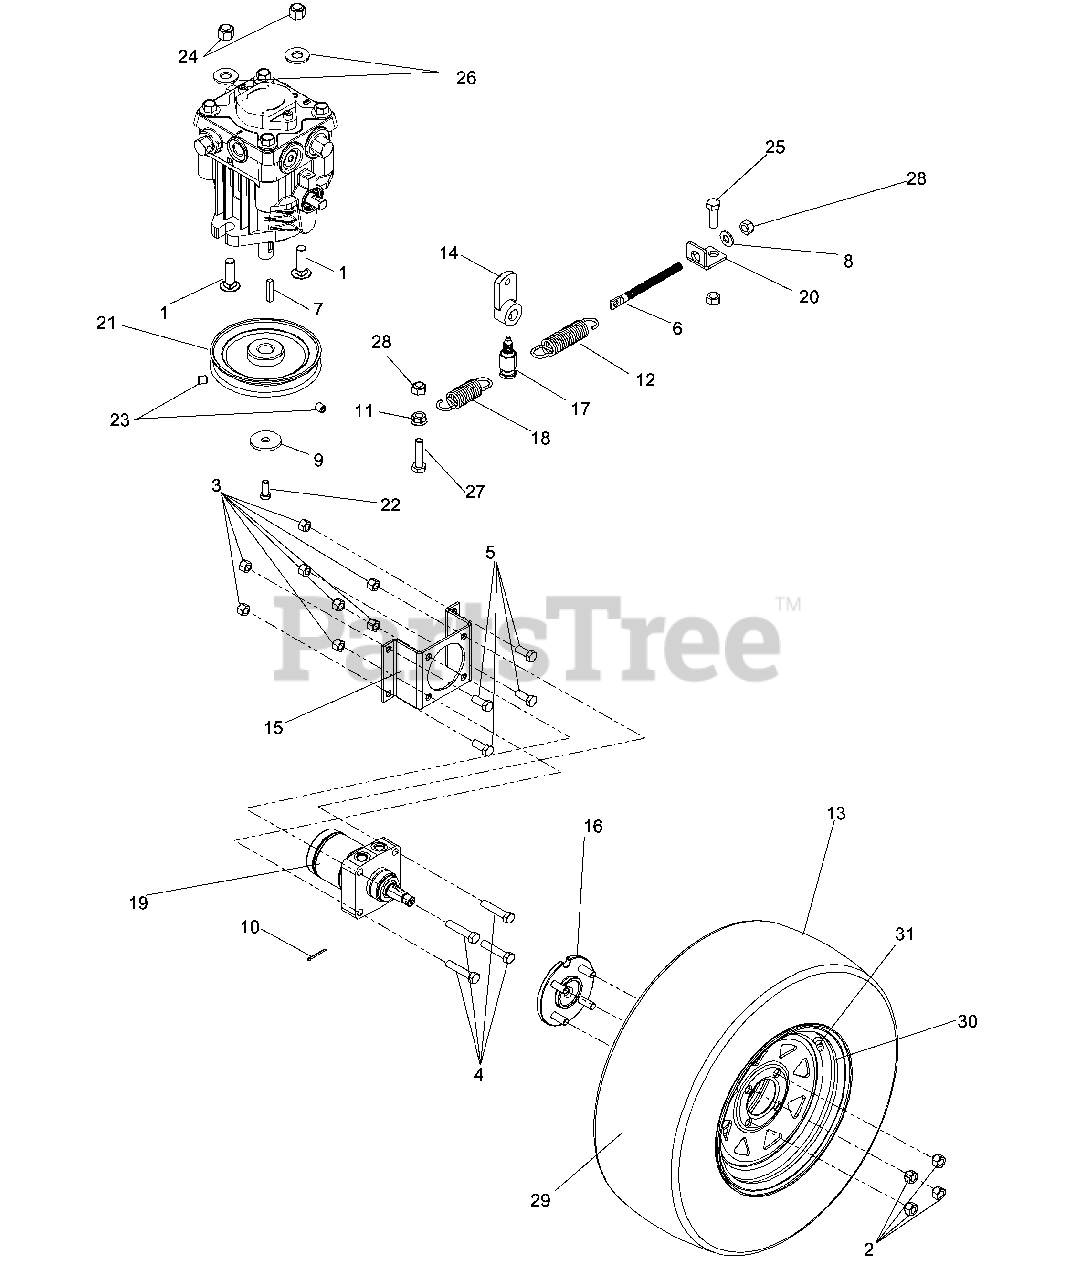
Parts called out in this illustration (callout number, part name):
1	RHSNB 3/8-16 X 1-1/4
2	LUG NUT 1/2F
3	NUT 1/2-13 HEX NYLOC ZD
4	HEX SCREW 1/2-13 X 2.5" GR 5
5	HCS 1/2-13 X 1-1/4
6	BRAKE ROD
7	KEY-3/16 DIA X 1
8	5/16STD FL WASH TYPA
9	5/16ID X 1/8THK WASHER
10	1/8DIAX1-1/2 COT PIN
11	5/16-18 FLANGED L-NUT
12	SPRING - 3.50
13	TIRE ASM 23X8.5-12
14	CONTROL ARM DRILLED
15	MT. MOTOR
16	HUB.WHEEL.ZTR
17	SET SCREW
19	WHEEL MOTOR
20	SPRING BRKT.
22	CAPSCREW HH 6MM X 16MM
23	SET SCREW 5/16 NYLOC
24	NUT 3/8-16 NYLOC
25	HCS 5/16C X 1
26	WASHER 3/8 FLAT
27	HCS 5/16C X 1 1/4
28	NUT 5/16 NYLOC
29	TIRE-REAR 23X8.5-12
30	RIM 12 X 7
